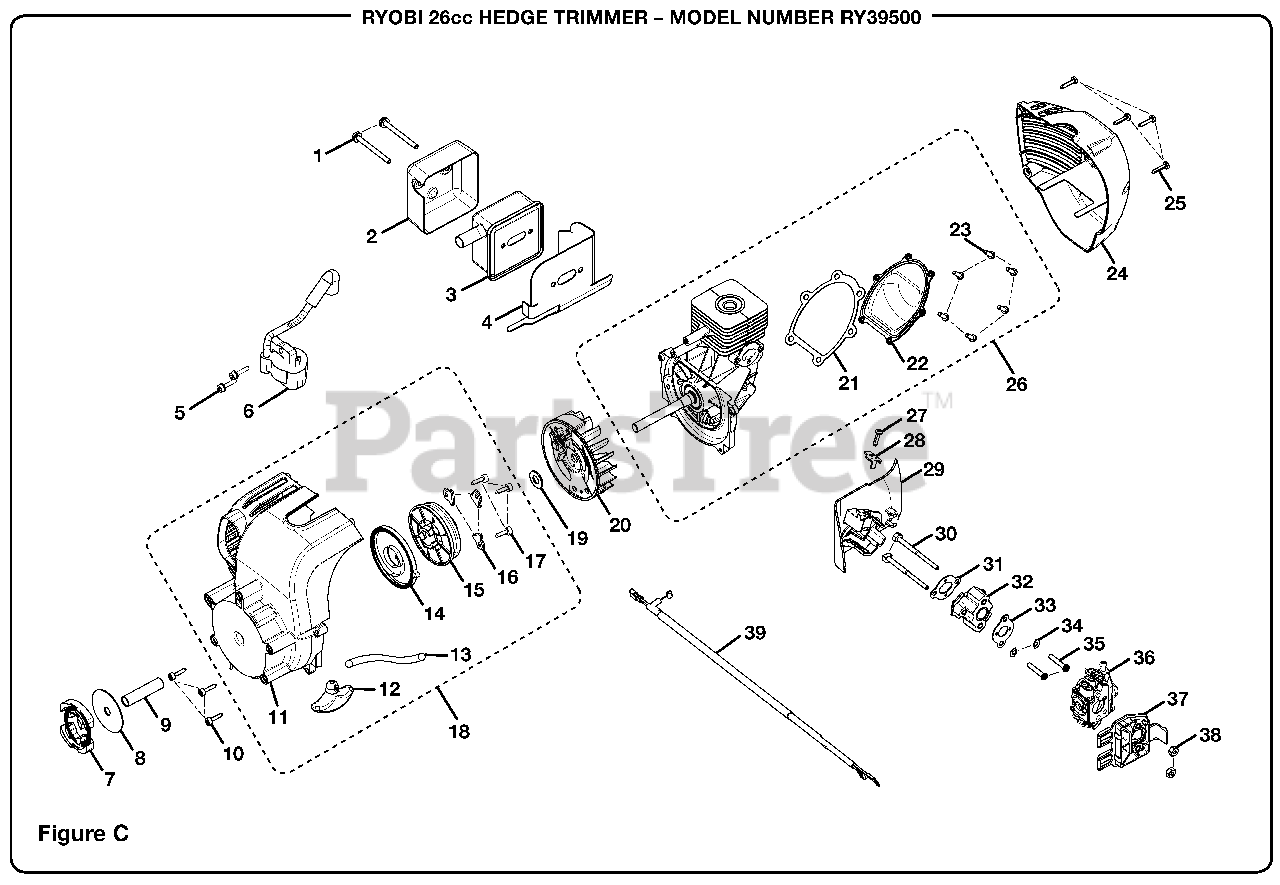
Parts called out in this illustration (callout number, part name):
1	Screw
2	Heat Shield
3	Muffler Assembly
4	Muffler Gasket
5	Screw
6	Ignition Module
7	Clutch Assembly
9	Spacer Tube
10	Screw
11	Lower Housing
12	Starter Grip
13	Starter Rope
14	Spring & Container Assembly
15	Starter Pulley
16	Pulley Retainer
17	Screw
18	Lower Housing Start Assembly
19	Washer
20	Flywheel Assembly
21	Crankcase Cover Gasket
22	Crankcase Cover
23	Screw
24	Upper Housing
25	Screw
26	Short Block Assembly
27	Screw
28	Clip Throttle Cable
29	Baffle Plate
30	Screw
31	Intake Gasket
33	Heat Dam Gasket
34	Washer
35	Screw
36	Carburetor
37	Air Box Base
38	Hex Nut
39	Throttle Cable And Lead Wire Assembly
